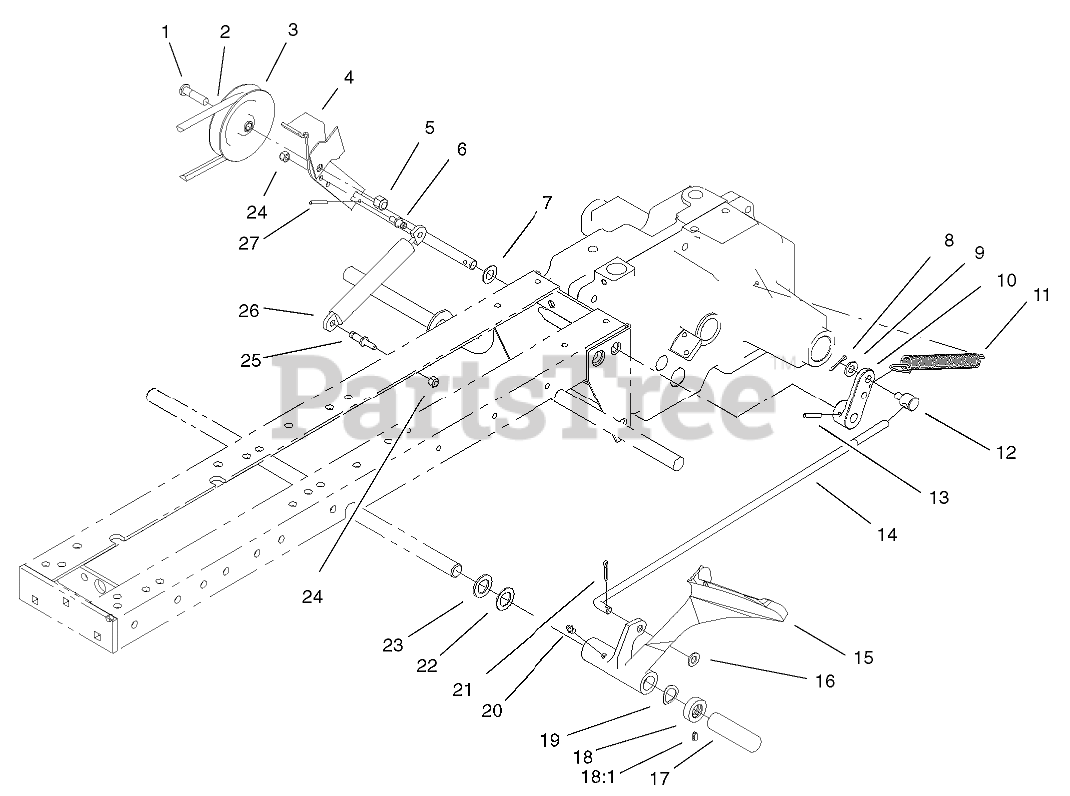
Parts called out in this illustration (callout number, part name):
1	BOLT-SPECIAL HEX
2	BELT-V IN
3	PULLEY-V, IDLER
4	IDLR ARM ASM
5	NUT-HEX
6	PIN-DAMPER, CLUTCH ARM
7	SHIM-WASHER
8	PIN-COTTER
9	WASHER-FLAT
10	ARM-CLUTCH ROD
11	SPRING-CLUTCH
12	TRUNNION
13	PIN-SPIROL
14	ROD AND GUIDE ASM
15	PEDAL-BRAKE, CLUTCH
16	WASHER-NYLON
17	SLEEVE-PROTECTIVE
18	COLLAR
18:1	SCREW-HSH
19	WASHER-BOWED
20	FITTING-GREASE
21	PIN-COTTER
22	WASHER
23	WASHER
24	NUT-LOCK, NI
25	PIN-DAMPER, CLASSIC FRAME
26	DAMPER-GAS
27	PIN-SPIROL
